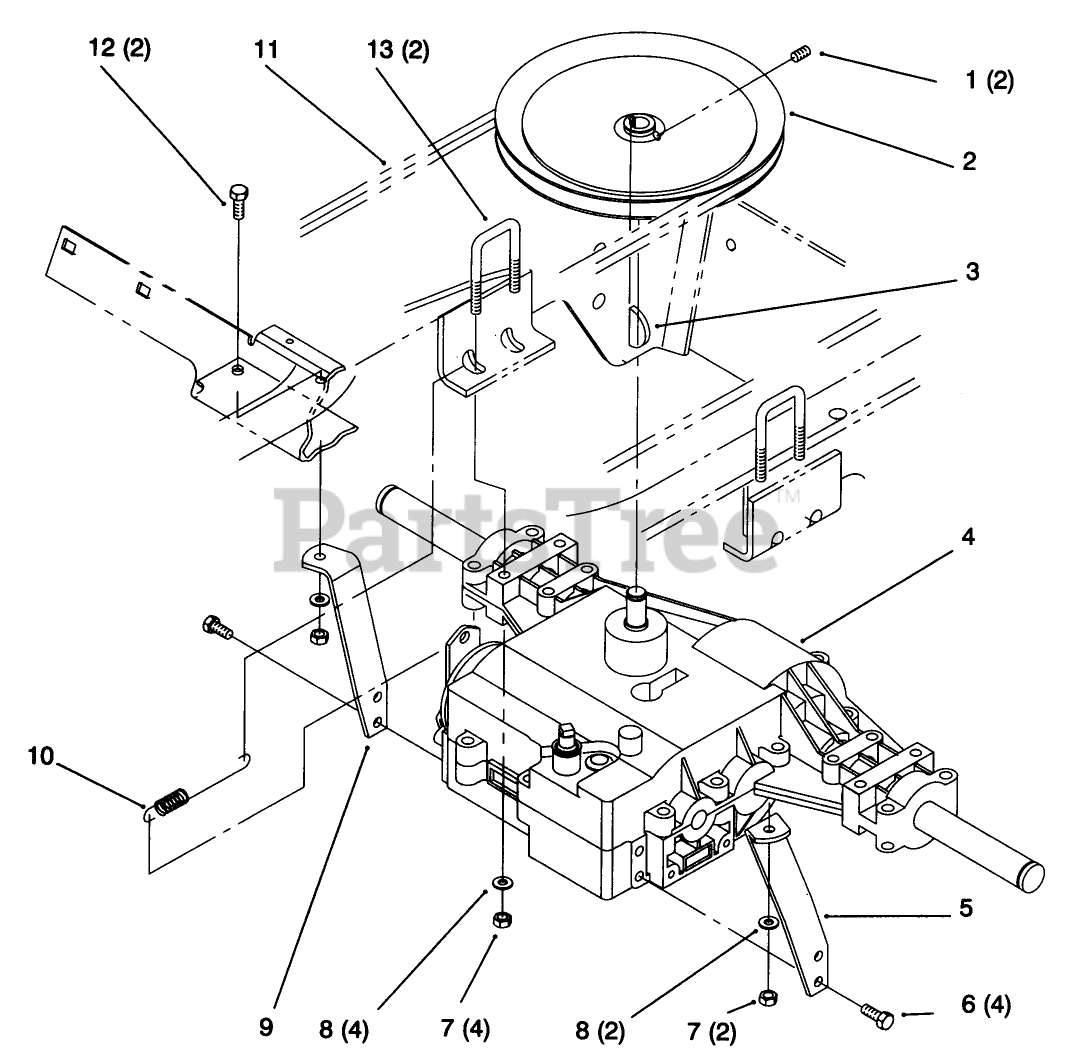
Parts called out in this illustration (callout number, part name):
1	SCREW-SQ HD SET
2	PULLEY-TRANS (GEAR)
3	KEY-HI-PRO
4	TRANSAXLE 820-024
5	STRAP - LH TORQUE
6	SCREW-HWHTF
7	NUT-LOCK, NI
8	WASHER-PLAIN
10	SPRING-EXTENSION
12	SCREW-HH
13	U-BOLT
